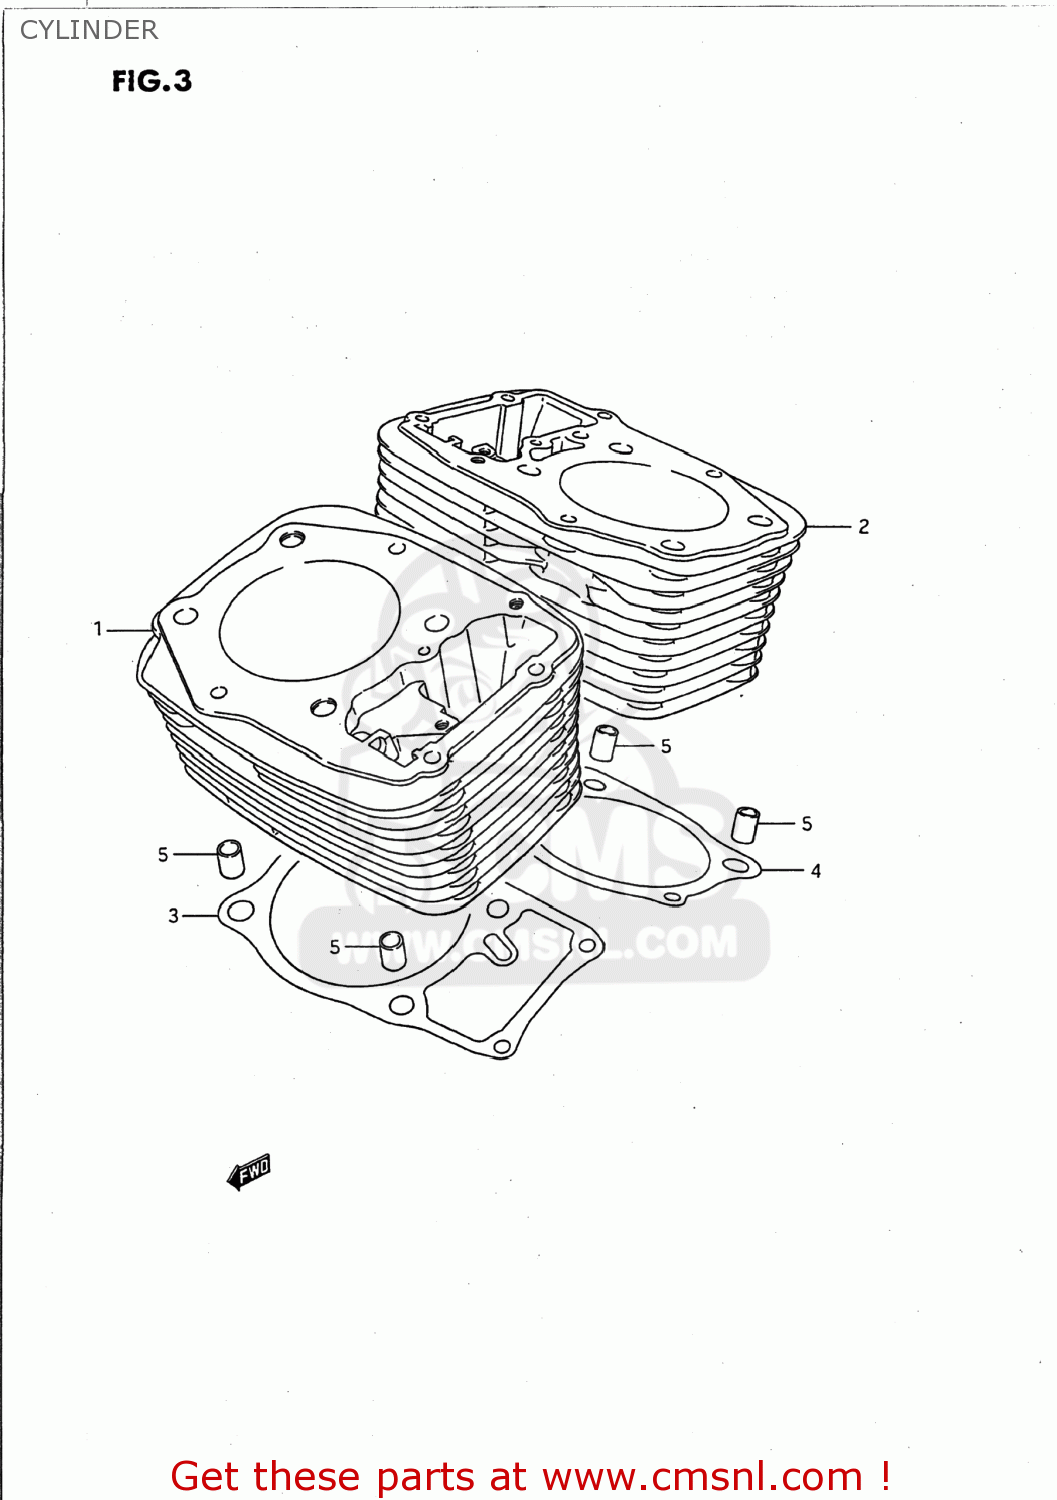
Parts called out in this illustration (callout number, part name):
1	CYLINDER
2	CYLINDER
3	GASKET,CYLINDER (NAS)
4	GASKET,CYLINDER (NAS)
5	PIN
